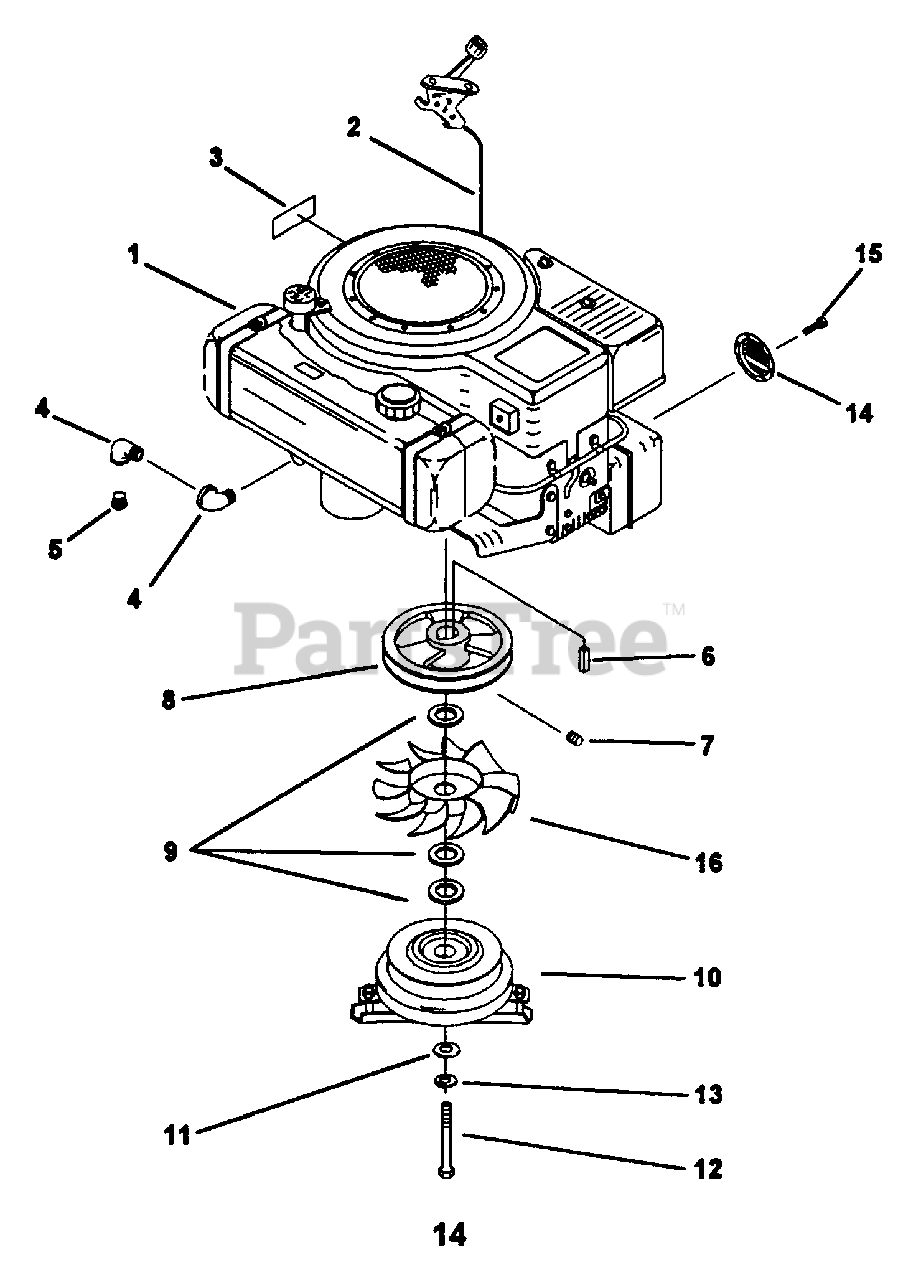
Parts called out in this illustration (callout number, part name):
1	ENGINE, 12 HP VERTICAL SHAFT
2	CABLE, CHOKAMATIC, 12 HP
3	DECAL "PERIODICALLY CLEAN"
4	ELBOW, STREET, 3/8", 90D. SCH. 40
5	PLUG, PIPE 3/8"
6	KEY. 1/4" SO. X 1"
7	SETSCREW. SOCKET HD. 5/16-18 X 3/8"
8	MOTOR DRIVE PULLEY
9	WASHER, SHIM
10	CLUTCH, ELECTRIC, 1" BORE
11	WASHER, 15/32" I.D.
12	CAPSCREW, 7/16-20 X 3-1/2" GR.5
12	CAPSCREW, 7/16-20 X 3" GR. 5
13	LOCKWASHER, 7/16" SPLIT SPRING
14	DEFLECTOR, LOUVERED
15	SCREW FOR DEFLECTOR
16	FAN, 7" DIA. 10 BLADE CW
